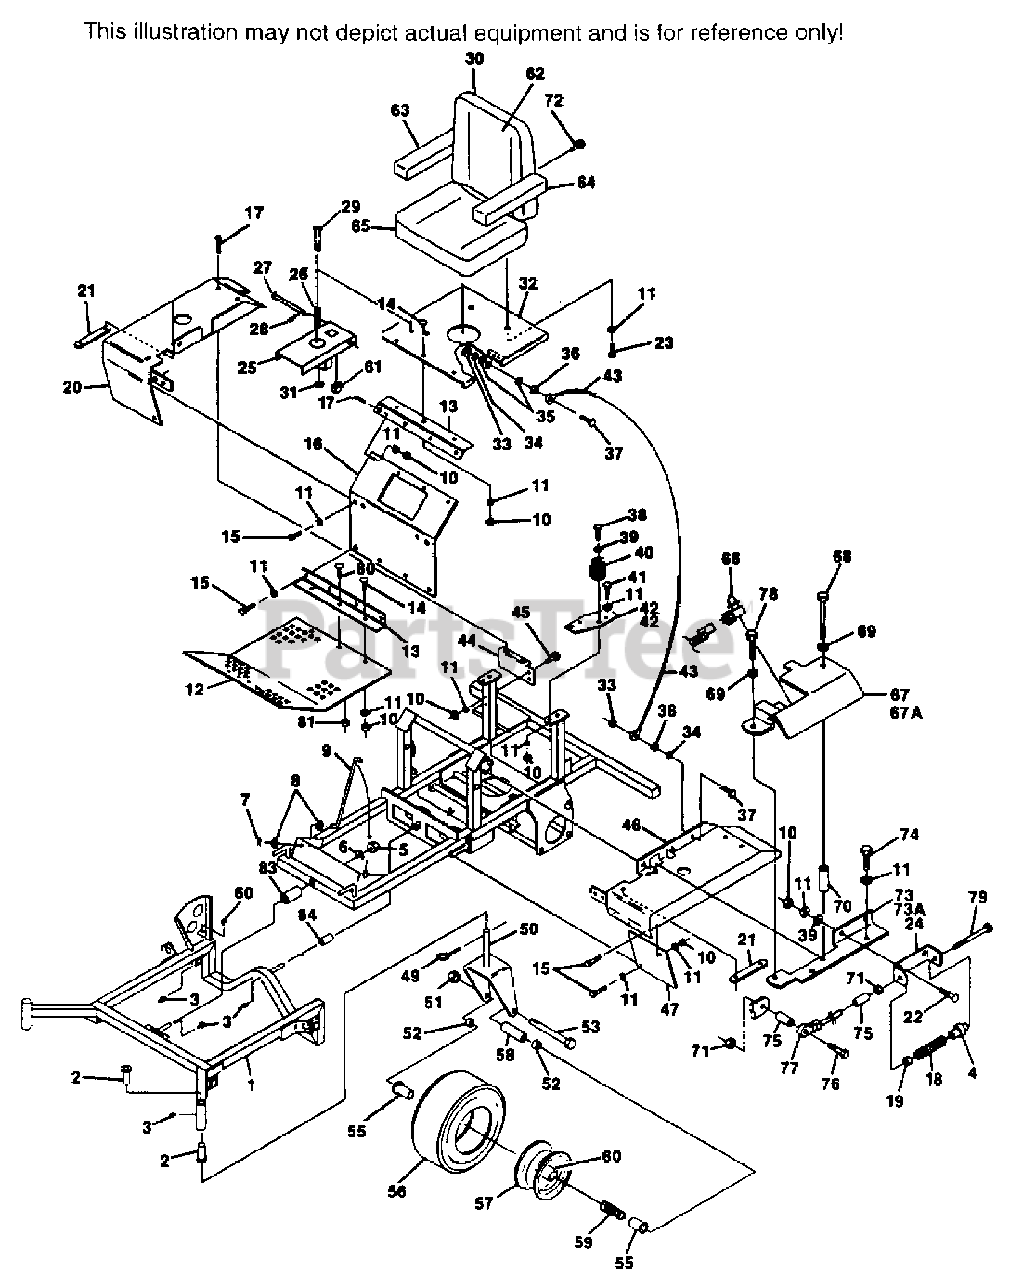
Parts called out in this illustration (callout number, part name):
1	CUTTER DECK SUPPORT FRAME ASSEMBLY
2	BUSHING
3	GREASE FITTING
4	SPACER, LONG
5	HEX NUT, 3/4-16 ELASTIC STOP
7	HAIR PIN, 1/16" DIA
9	ROD, FOOT PLATE LATCH
12	FOOT PLATE
13	HINGE
16	KICK PLATE
18	NEUTRAL RETURN SPRING
19	SPACER, SHORT
20	FENDER ASSEMBLY - RH(W/DECALS)
21	NEUTRAL LOCK BAR
22	CARRIAGE BOLT, 5/16-18 X 1"
24	RETAINER, NEUTRAL SPRING
25	SEAT SWITCH BRACKET
26	SPRING
27	CLEVIS PIN
28	HAIR PIN COTTER
30	SEAT
31	HEX NUT, 5/16-18 ELASTIC STOP
32	SEAT BASE
33	HEX NUT, 1/4-20 ELASTIC STOP
40	SEAT SPRING
42	OIL COOLER MOUNTING BRACKET - LH
43	CABLE, SEAT STOP
44	FENDER BRACKET - RH & LH
46	FENDER ASSEMBLY - LH(W/DECALS)
47	LH FENDER EXTENSION
49	QUICK PIN
50	CASTER WHEEL YOKE
51	HEX NUT, 1/2-13 ELASTIC STOP
52	SPACER
55	RETAINER
56	TIRE ONLY
57	RIM ONLY
58	SLEEVE
59	ROLLER BEARING
60	GREASE FITTING
61	SEAT SWITCH
62	SEAT BACK CUSHION
63	ARM PAD - RH
64	ARM PAD - LH
65	CUSHION ASSEMBLY
66	NEUTRAL INTERLOCK SWITCH
67	RH NEUTRAL LOCK BRACKET
67A	LH NEUTRAL LOCK BRACKET
71	HEX NUT, 3/8-24 UNF
72	HEX HEAD SCREW W/WASHER, 1/4-20 X 3/4"
73	LH NEUTRAL CONTROL MOUNTING BRACKET
73A	RH NEUTRAL CONTROL MOUNTING BRACKET
75	SPACER NEUTRAL SPRING
77	BALL JOINT, NEUTRAL
79	HEX HEAD BOLT, 3/8-24 X 6 3/4" SPECIAL
83	BUSHING
